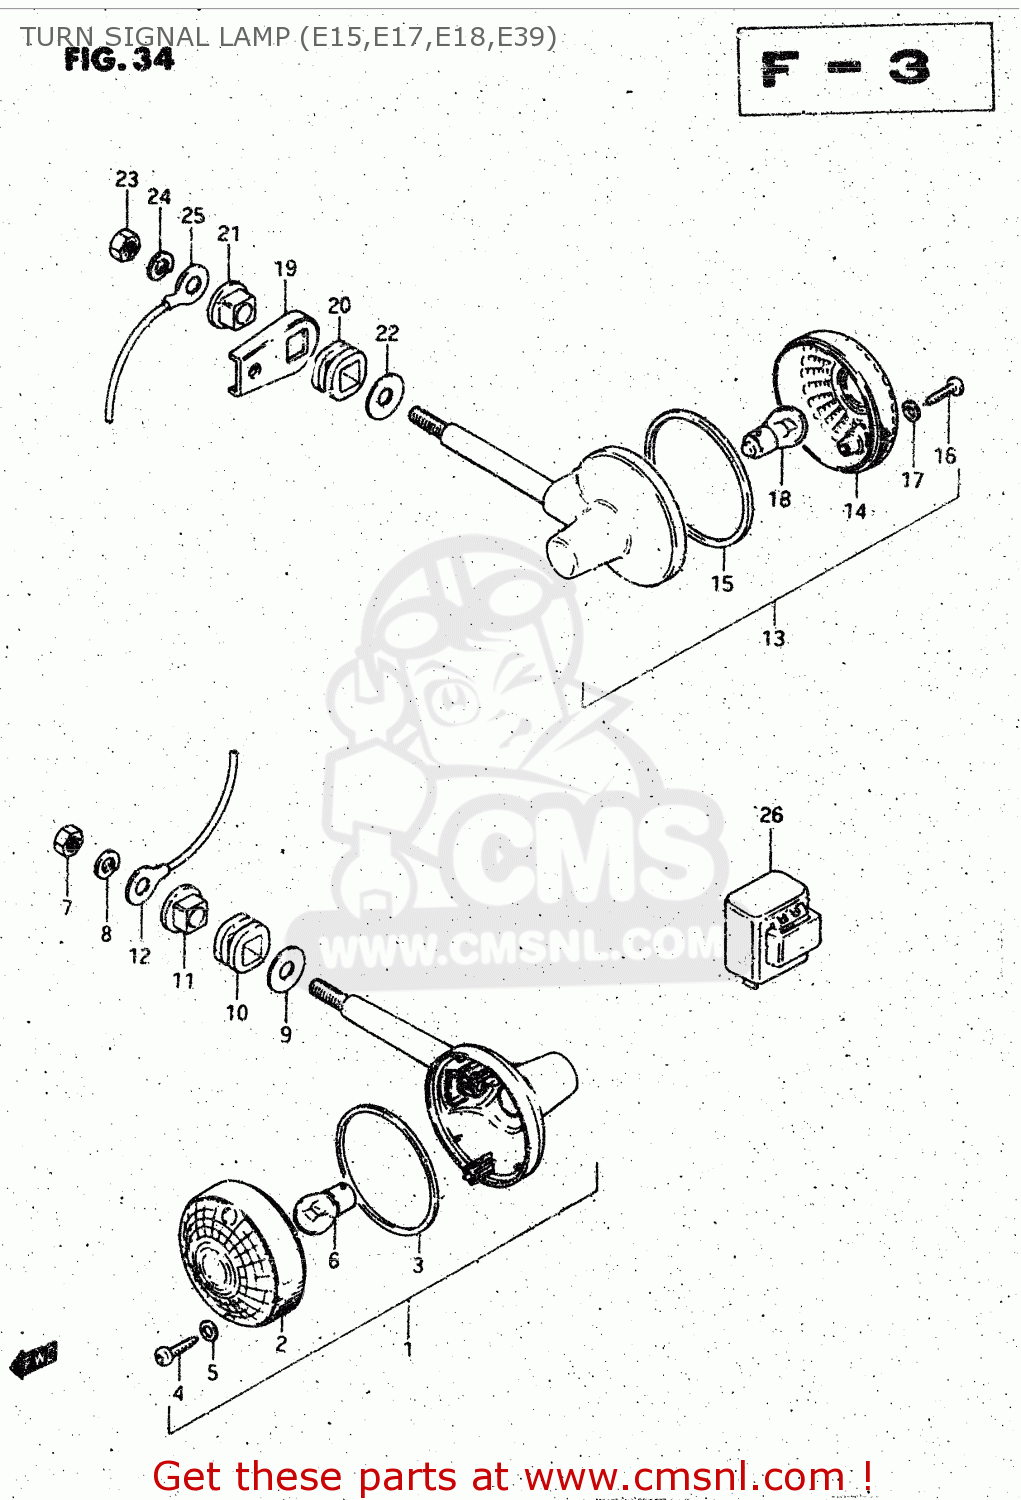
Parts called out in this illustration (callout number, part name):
1	LAMP ASSEMBLY,FRONT TURN SIGNAL
2	LENS
3	GASKET (NAS)
4	SCREW
5	GASKET (NAS)
6	BULB(12V21W)
7	NUT
8	LOCK WASHER
9	WASHER (10.5X30X2.3)
10	CUSHION
11	SPACER
12	LEAD WIRE,EARTH
13	LAMP ASSY, REAR TURN SIGNAL
14	LENS
15	GASKET (NAS)
16	SCREW
17	GASKET (NAS)
18	BULB(12V21W)
19	BRACKET,RR TURNSIGNAL LAMP
20	CUSHION
21	SPACER
22	WASHER (10.5X30X2.3)
23	NUT
24	WASHER,LOCK,10
25	LEAD WIRE,EARTH
26	RELAY ASSEMBLY,TURN SIGNAL
